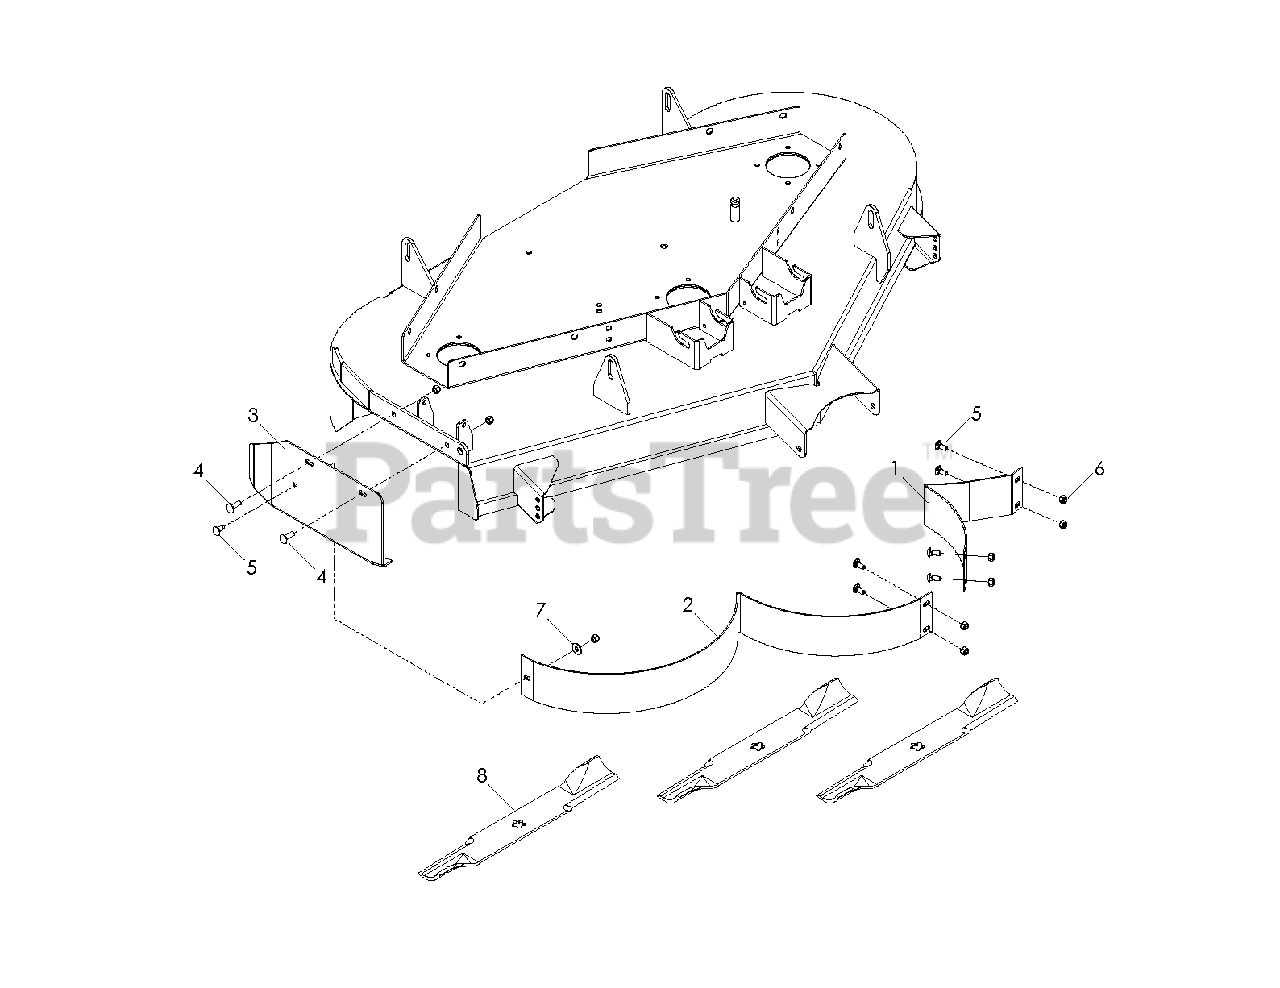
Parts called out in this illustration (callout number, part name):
1	52 MULCH BAFFLE - L.H. PAINTED
2	MULCH BAFFLE RH 52 - PAINTED
3	52 MULCH CAP - PAINTED
4	SCREW 5/16C X 1 HEX CAP
5	BOLT 5/16C X 3/4" CARRIAGE
6	NUT 5/16 NYLOC
7	WASHER 5/16 FLAT
8	BLADE 18" GATOR
